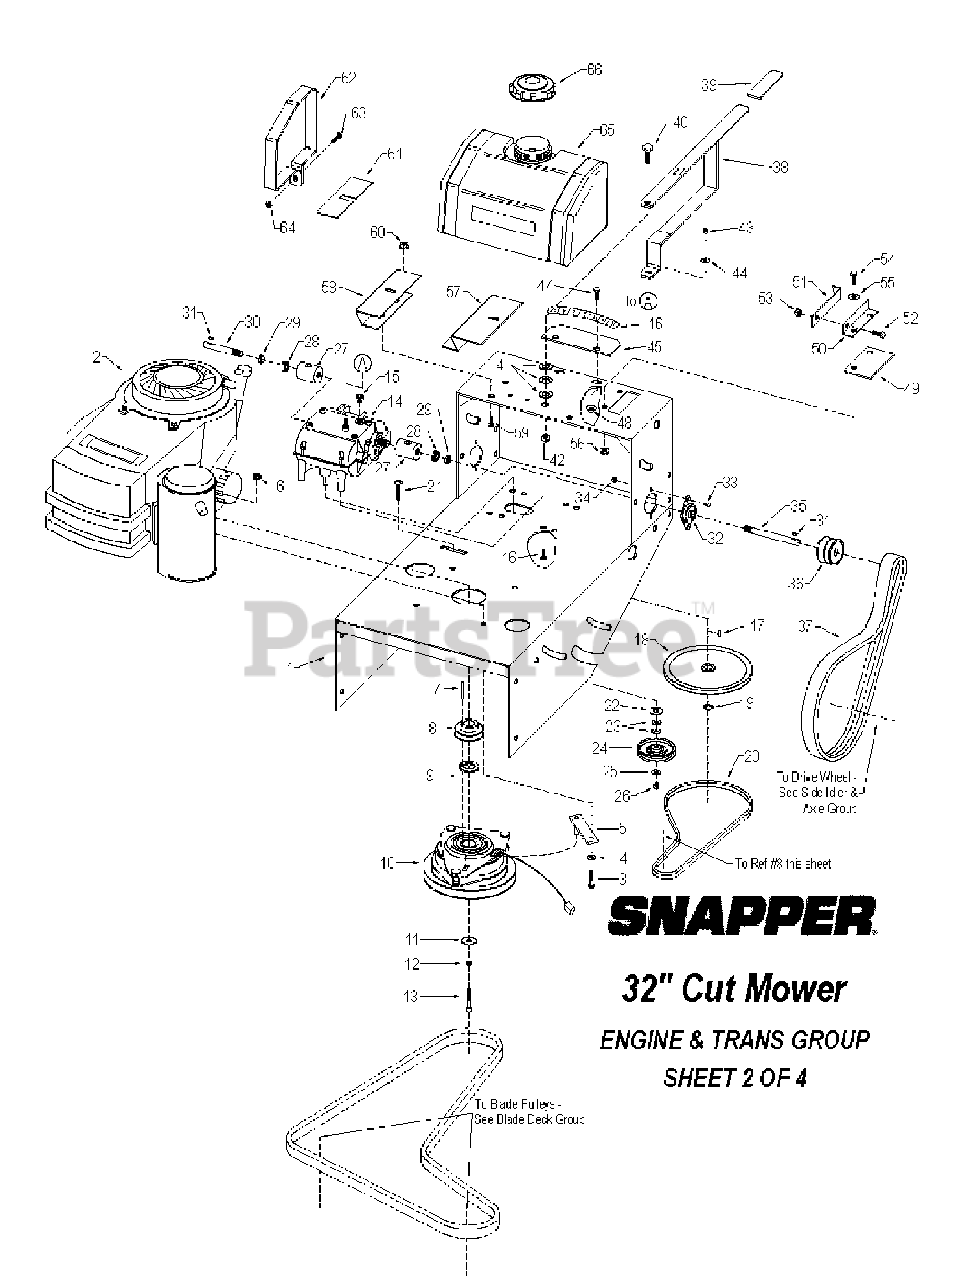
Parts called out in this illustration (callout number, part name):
1	Engine base
2	Engine, 13 HP Kawasaki w/5 amp coil
3	5/16-18 x 1-1/2" hex bolt
4	5/16 flat washer
5	Blade clutch anti-torque pin
6	5/16-18 small serrated flange nut
7	Engine shaft key - 1/4" x 1-7/8"
8	Engine-to-trans pulley
9	1/4" spacer
10	Electric blade clutch
11	7/16" heavy duty washer
12	7/16" lock washer
13	7/16-20 x 2" socket head cap screw
14	Transmission
15	Transmission ball switch
16	5/16-18 x 3/4" 'F' thread bolt
17	#9 woodruff key
18	Transmission pulley
19	5/8" snap ring
20	Transmission belt
21	Trans idler bolt
22	3/8" flat washer
23	5/16" SAE washer
24	Trans idler pulley
25	5/16" flat washer
26	3/8-16 lock nut
27	Trans axle coupler
28	5/8" locking collar
29	1/4" spacer
30	Trans axle - right
31	#9 woodruff key
32	5/8" bearing unit
33	1/4-20 x 5/8" hex bolt
34	1/4-20 serrated flange nut
35	Trans axle - left
36	2-V drive pulley
37	2-V drive belt
38	Shift lever
39	Handle grip - 1/4" x 1-1/4" x 4-1/2"
40	1/2-13 x 2-1/2" hex bolt
41	1/2" oillite washer
42	1/2-13 nylon lock nut
43	3/8-24 nylon lock nut
44	3/8" flat washer
45	Shift panel
46	Shift decal
47	5/16-18 x 3/4" hex bolt
48	5/16-18 small serrated flange nut
49	Manual blade engagement hole cover plate
50	Reverse lockout bracket
51	Reverse lockout bar
52	5/16-18 x 3/4" hex bolt
53	5/16-18 lock nut
54	5/16-18 x 1" hex bolt
55	5/16 flat washer
56	5/16-18 small serrated flange nut
57	Fuel tank mount - left
58	Fuel tank mount - right
59	5/16-18 x 3/4" hex bolt
60	5/16-18 small serrated flange nut
61	Slotted rubber fuel tank pad
62	Fuel tank strap
63	1/4-20 x 1-1/2" hex bolt
64	1/4-20 serrated flange nut
65	Fuel tank
66	Fuel cap
